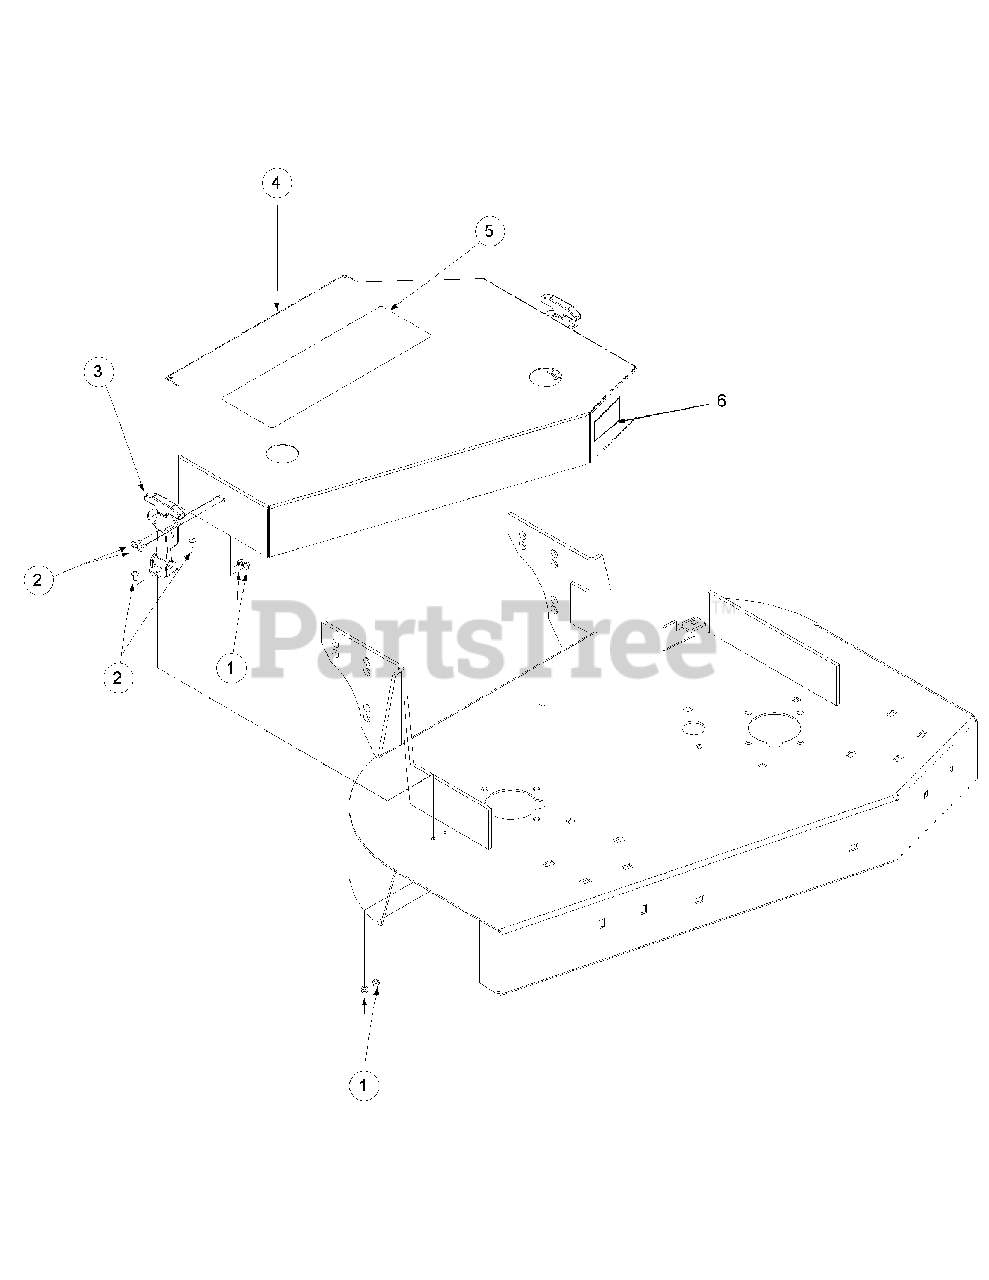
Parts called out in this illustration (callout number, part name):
1	Lock Nut, Nylon Insert
2	Machine Screw, 10-24 x 1/2
3	Rubber Hood Latch
4	Deck Cover, 36
5	Label Commercial Mower
